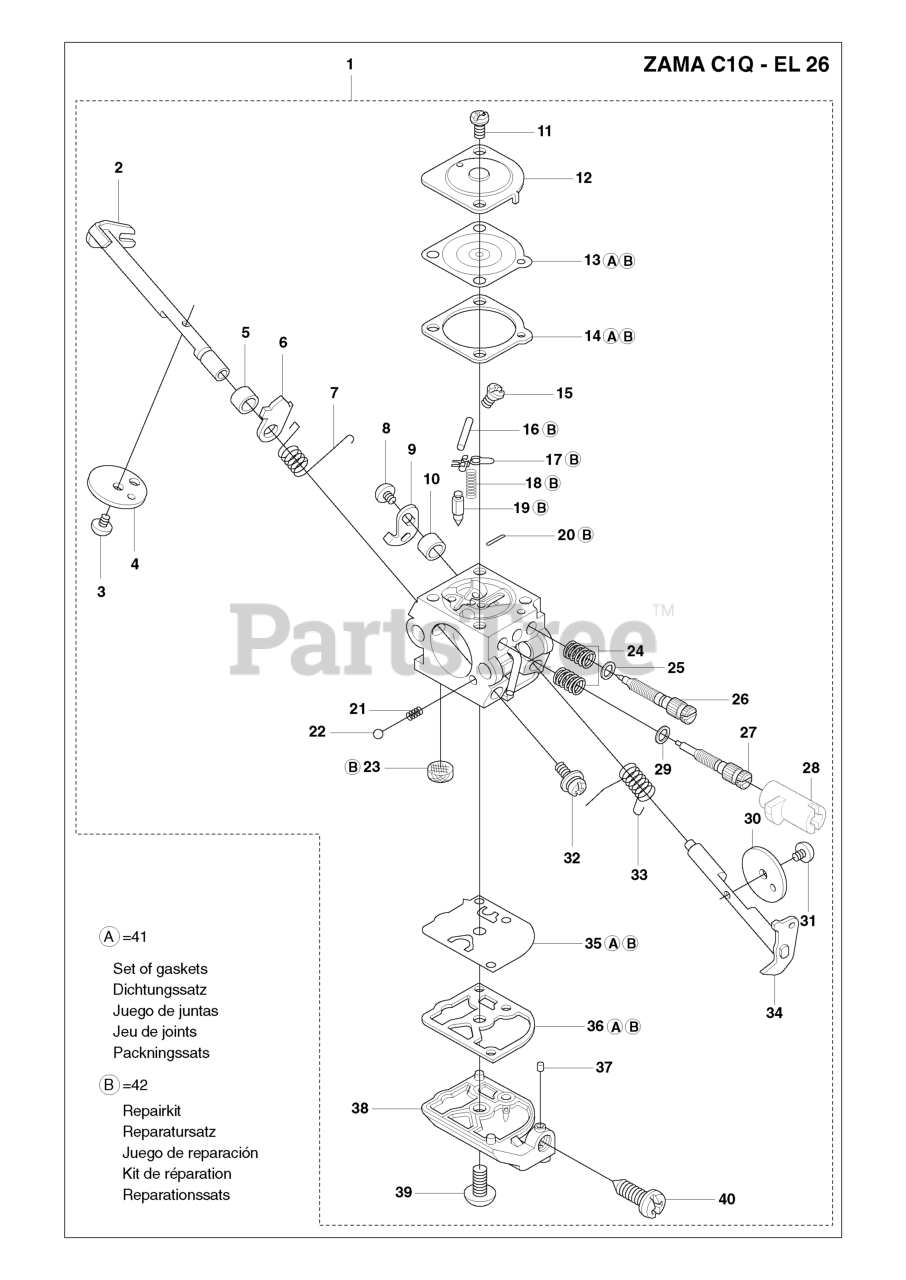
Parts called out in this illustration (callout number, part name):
1	BLADE
2	CUTTER ASSY
4	NUT
5	NUT
7	WASHER 6,4X18X1,5
8	WASHER 6,4X18X1,5
9	SCREW
10	SCREW
11	PLATE
12	BALK
13	BLADE
14	BLADE
15	PROTECTOR
16	PROTECTOR
18	NUT
20	RP SHOULDER BOLT
21	WASHER 6,4X18X1,5
